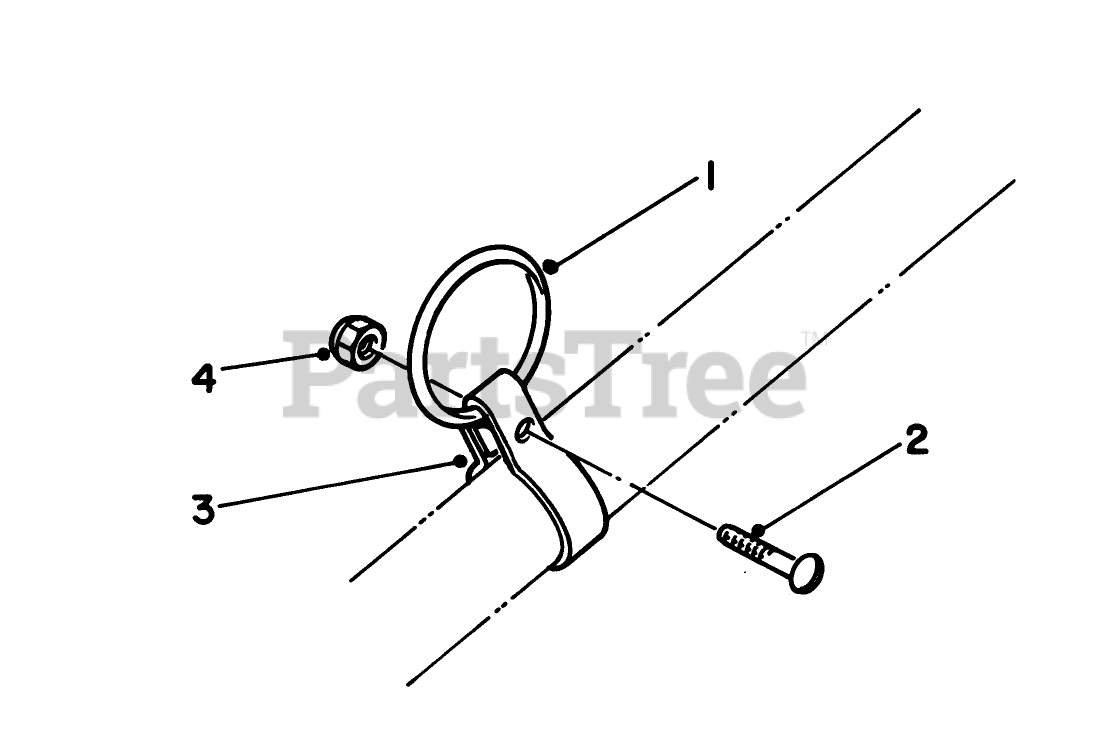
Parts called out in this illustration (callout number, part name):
1	Ring
2	SCREW-SRH
3	Clamp
4	Nut
